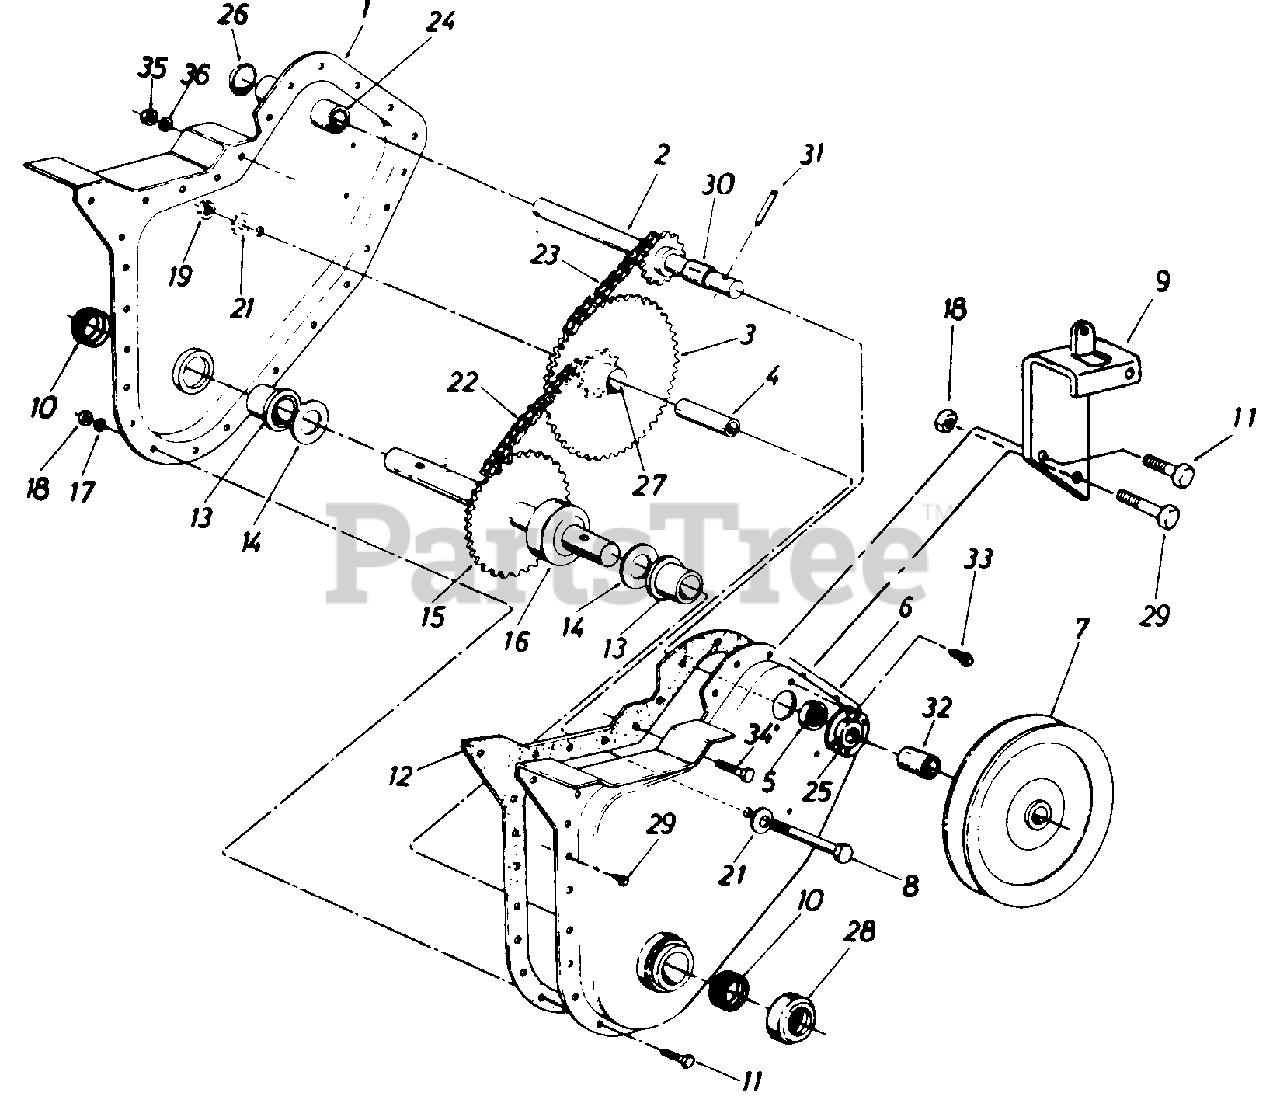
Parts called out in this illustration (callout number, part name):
1	Chain Case Ass'y.-R.H.
2	Input Shaft Ass'y.
3	Hub and Sprocket Ass'y.
4	Bearing Inner Race
5	Ball Bearing
6	Chain Case Ass'y.-L.H.
7	Pulley-Chain Case
8	Hex Bolt 3/8-24 x 2.5"*
9	Fuel Tank Brkt
11	Hex Bolt 1/4-28 x .625"*
12	Gasket
13	Flange Brg. .879" I.D.
14	Fl-Wash. .88" I.D. x 1.5"
15	Tine Shaft Ass'y.
16	Spacer 7/8" I.D.
17	L-Wash. 1/4" I.D.
18	Hex Nut 1/4-28 Thd.*
19	Hex Ins. L-Nut 3/8-24 Thd.
21	Bell-Wash. .406" I.D.
22	Chain #420 '/2" Pitch 38 0 Links
23	Chain #35 .375" Pitch 50 0 Links
24	Bearing .62" I.D. x .813"
25	Bearing Housing
26	Expansion Plug 13/16" Dia.
27	Bearing
29	Hex Wash. Hd. Self-Tap Scr. 1/4-20 x .50" Lg.
30	Spacer .63" I.D. x .77" O.D. x .38" Lg.
31	Spring Pin Spiral 1/4" Dia. x 11/2" Lg.
32	Spacer .647 x 1.25"
33	Hex Wash. Hd. Self-Tap Scr. 1/4-20 x .38" Lg.
34	Hex Bolt 5/16-18 x .75"*
35	Hex Nut 5/16-18 Thd.
36	L-Wash. 5/16" I.D.*
